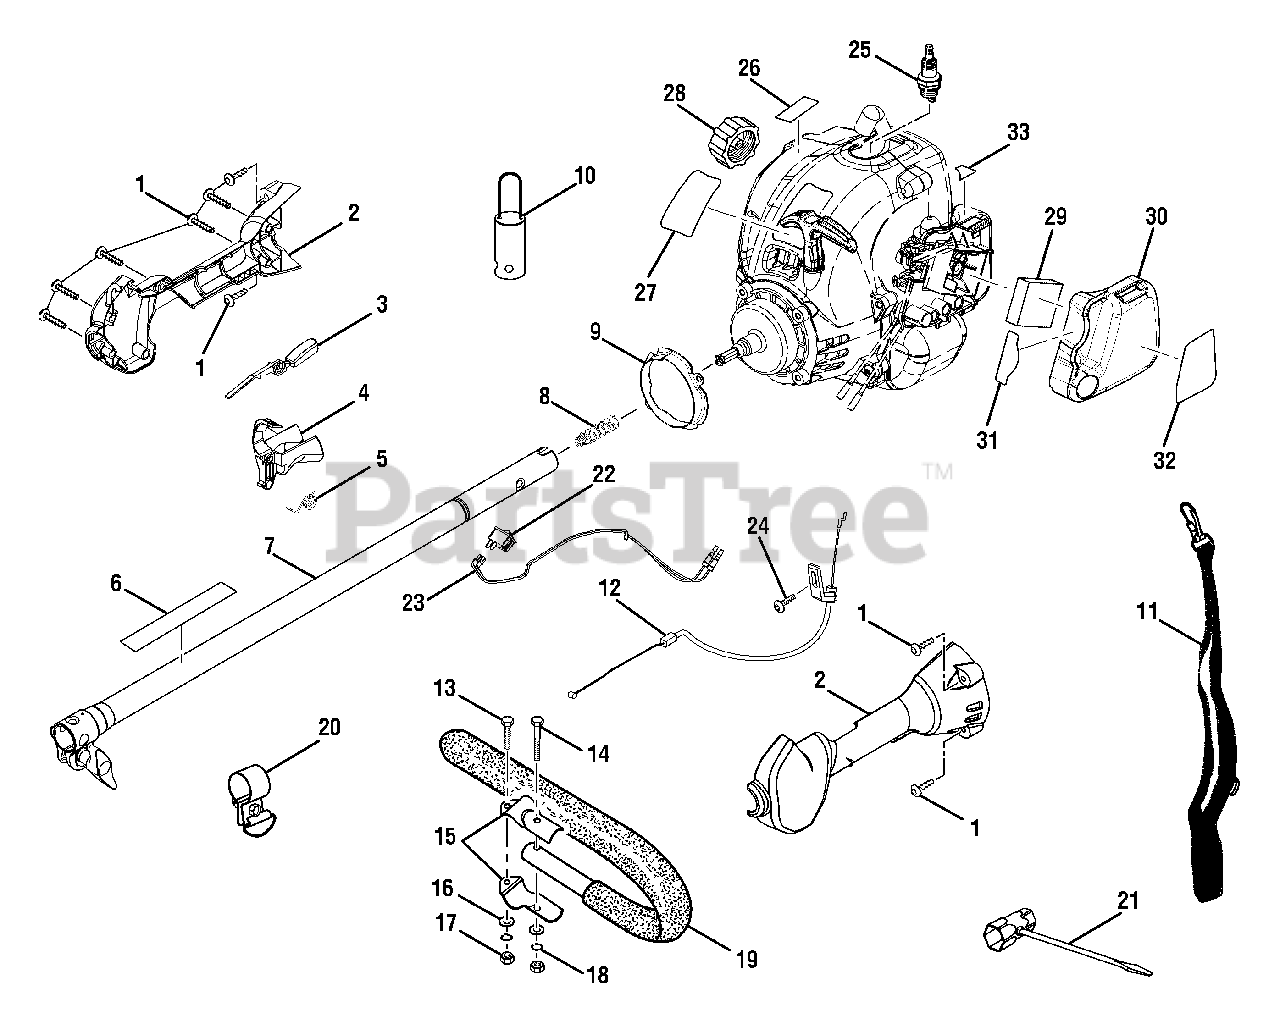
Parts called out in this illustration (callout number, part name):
1	SCREW (10-14 X 1 in. T.F. TRUSS HD.)
2	HANDLE ASSEMBLY
3	TRIGGER LOCK
5	TORSION SPRING
6	WARNING LABEL
7	BOOM ASSEMBLY
8	COMPRESSION SPRING
9	RING GUARD
10	STORAGE END CAP
11	SHOULDER STRAP
12	THROTTLE CABLE ASSEMBLY
13	BOLT (1/4-20 X 1 in. HEX HD.)
14	BOLT (1/4-20 X 1-1/2 in. HEX HD.)
15	HANDLE BAR CLAMP
16	WASHER
17	HEX NUT (1/4-20)
18	LOCK WASHER
19	J HANDLE AND GRIP
20	STRAP HANGER
21	COMBINATION WRENCH
22	SWITCH (MOMENTARY CONTACT)
23	LEAD ASSEMBLY
25	SPARK PLUG (CHAMPION RCJ6Y OR NGK BPM R7)
26	LOGO LABEL
27	MODEL LABEL
28	FUEL CAP ASSEMBLY
29	AIR FILTER
30	AIR BOX COVER
31	CHOKE DECAL
32	STARTING LABEL
33	PRIMER LABEL
